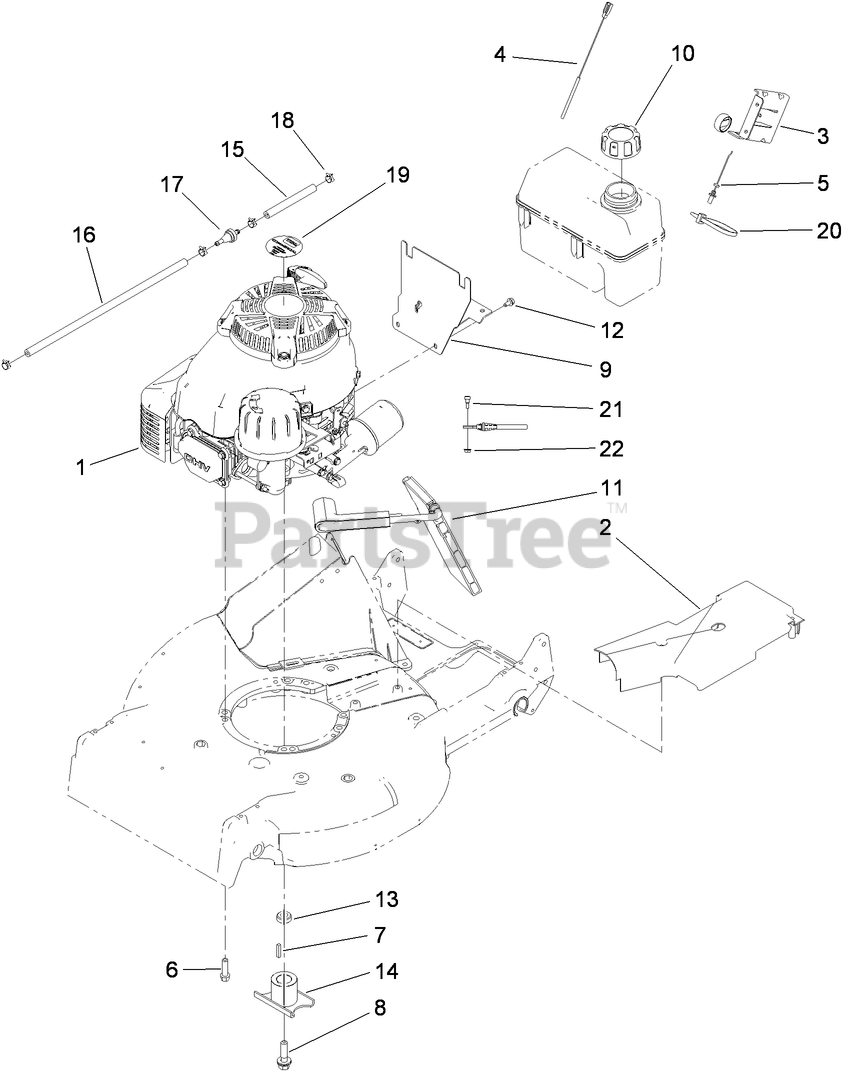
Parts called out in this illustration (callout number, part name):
1	ENGINE-KAWASAKI, FJ180V-AM08-M
2	COVER-BELT
3	CONTROL-HEAD, THROTTLE
4	CABLE-BRAKE, CONTROL
5	THROTTLE CABLE ASM
6	SCREW-TAPTITE
7	KEY-SQUARE
8	BOLT-BLADE
9	MOUNT-TANK
10	CAP-GAS
11	DISCHARGE DOOR ASM
12	SCREW-HWH
13	Spacer-Retainer, Blade
14	RETAINER-BLADE
15	HOSE-FUEL
16	HOSE-FUEL
17	FILTER-FUEL
18	CLAMP-HOSE
20	TIE-CABLE
21	SCREW-SHOULDER
22	NUT-LOCK, FLANGE
